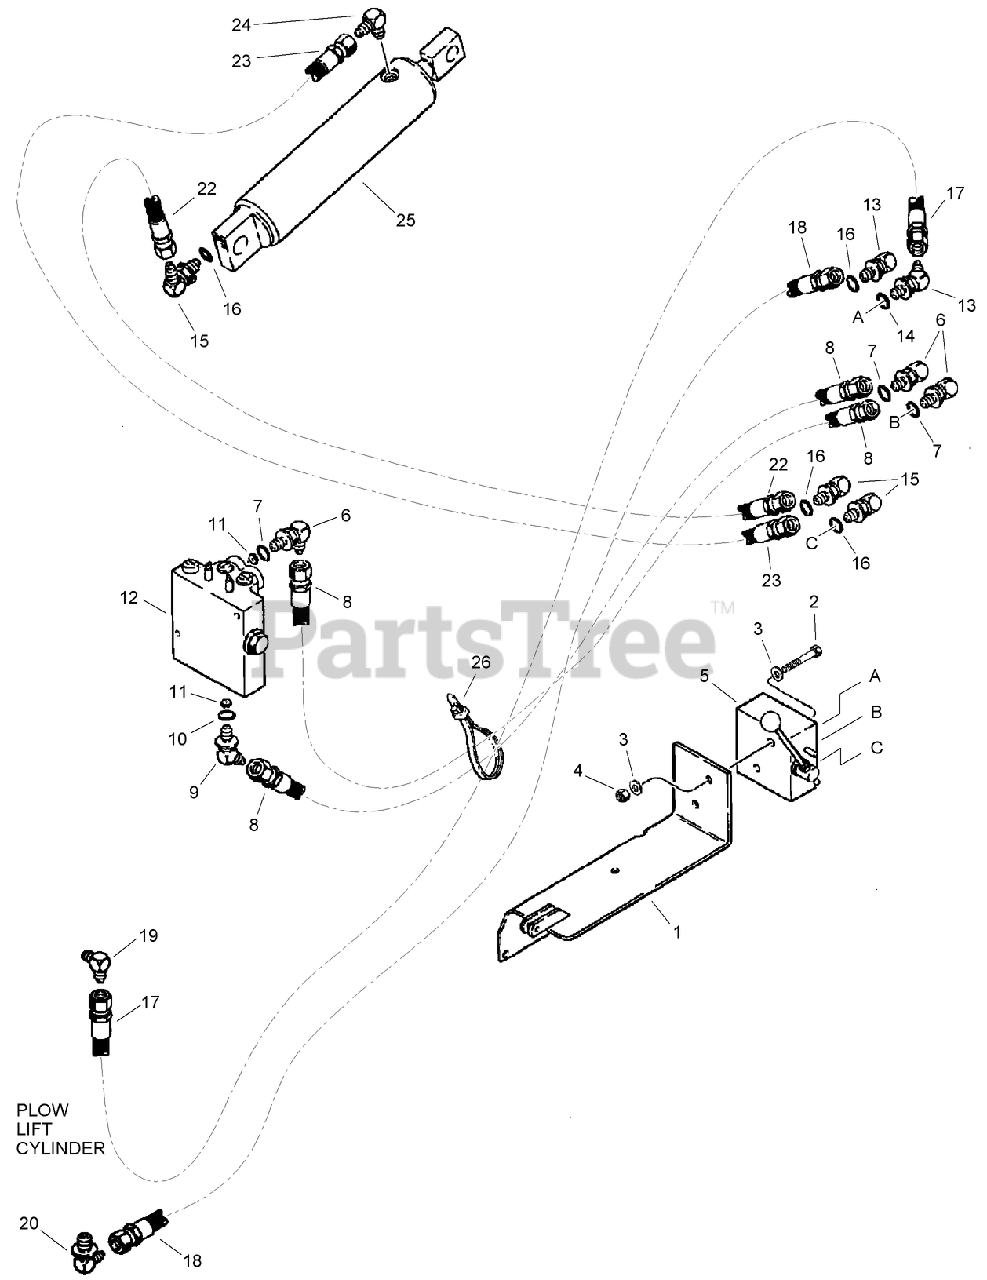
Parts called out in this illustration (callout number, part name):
1	BRACKET - Switch and Valve Mounting
3	WASHER-0.406 x 0.812 x 0.065 in CST ZND
4	NUT-HEX
5	HYD CONTROL VALVE ASM
6	ELBOW-90 DEG (ADJUSTABLE 37 DEG)
8	HOSE - 610 mm (24 inch) Long, from Plow Lift Ports on Steering Control Valve
9	ELBOW-45 Adj 37FL 3/8 Tube
11	ORIFICE
12	HYD STEERING VALVE ASM
13	ELBOW-90 Deg
15	ELBOW-90 DEG (ADJUSTABLE 37 DEG)
17	HOSE - 533 mm (21 inch) Long, Upper Right-hand Port of Selector Valve to Rod End of Plow Lift Cylinder
18	HOSE - 457 mm (18 inch) Long, Upper Left-hand Port of Selector Valve to Closed End of Plow Lift Cylinder
19	ELBOW - 90, 37FL 3/8 Tube x 3/8 NPFT
20	ELBOW-90 Adj 37FL, 3/8 x 1/2 Tube
22	HOSE - 2050 mm (80-11/16 inch) Long, Lower Left-hand Port of Selector Valve to Closed End of Trencher Lift Cylinder1
23	HOSE - 2250 mm (88-5/8 inch) Long, Lower Right-hand Port of Selector Valve to Rod End of Trencher Lift Cylinder
24	ELBOW - 90, 37FL 3/8 Tube x 3/8 NPFT
25	HYD CYLINDER ASM
26	STRAP - Tie, 15 inch, Nylon, Retaining
